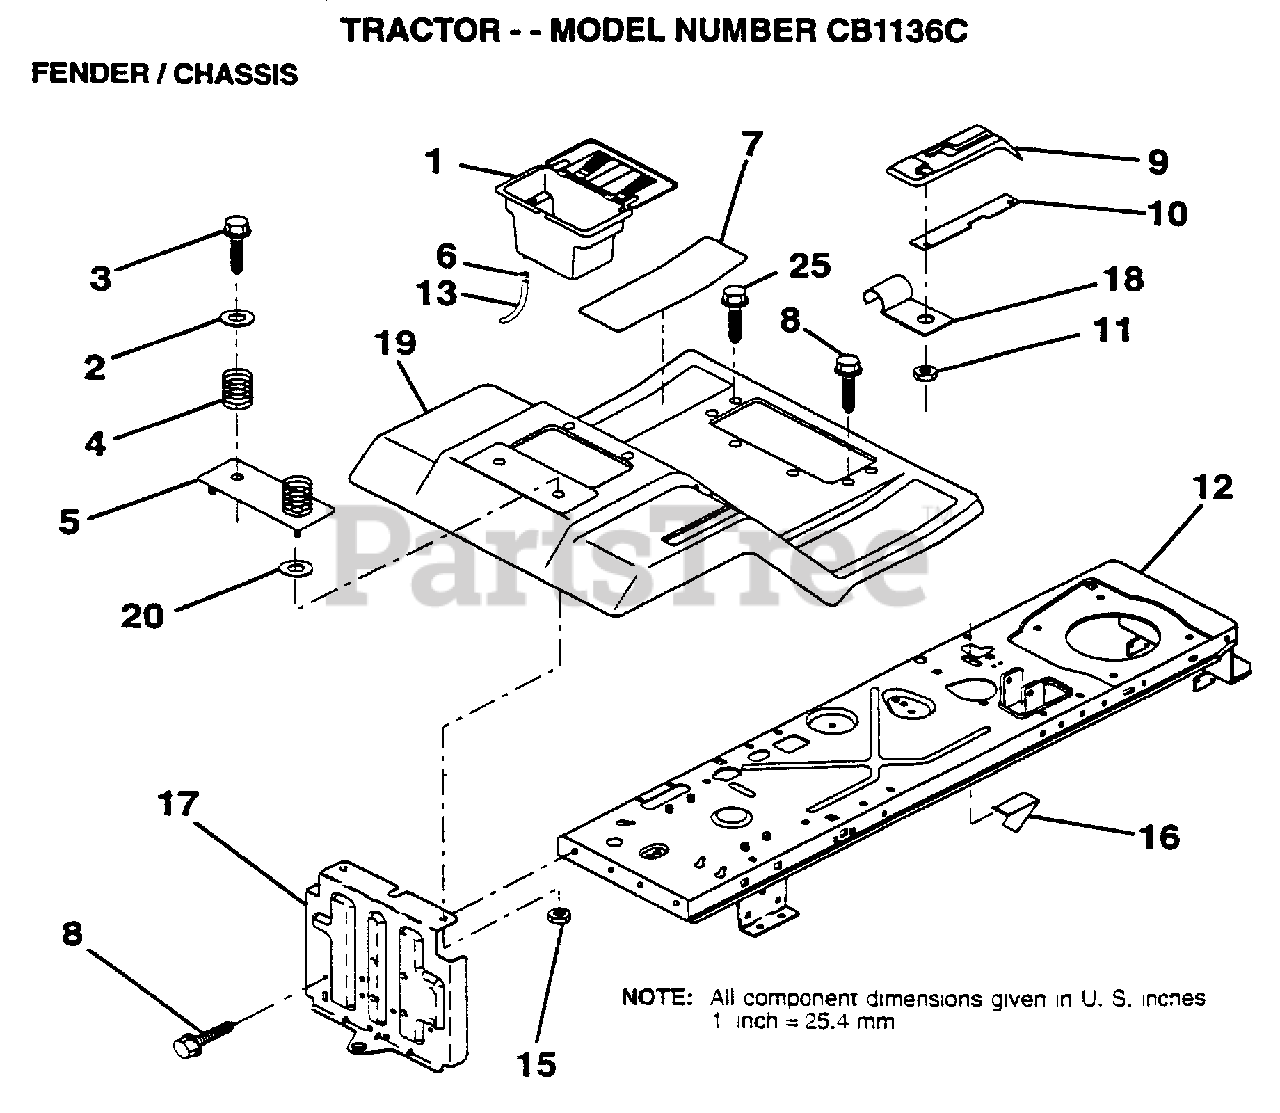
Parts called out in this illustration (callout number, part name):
2	WASHER
3	SCREW
4	SPRING COMPRESSIO
5	BTRY FENDER PLATE
6	HOSE CLAMP T
7	PAD FOOTREST
8	SCREW
9	CONSOLE SHFT 5SP
10	PLATE LOCK SHIFT
11	NUT
12	CHASSIS.WELD.ASM.
13	TUBE T
14	NUT
15	NUT HXKEP 1/4X20
17	DRAWBAR ASM LR
18	"CLIP,INSULATOR"
19	FENDER/FOOT MS505
25	SCREW
